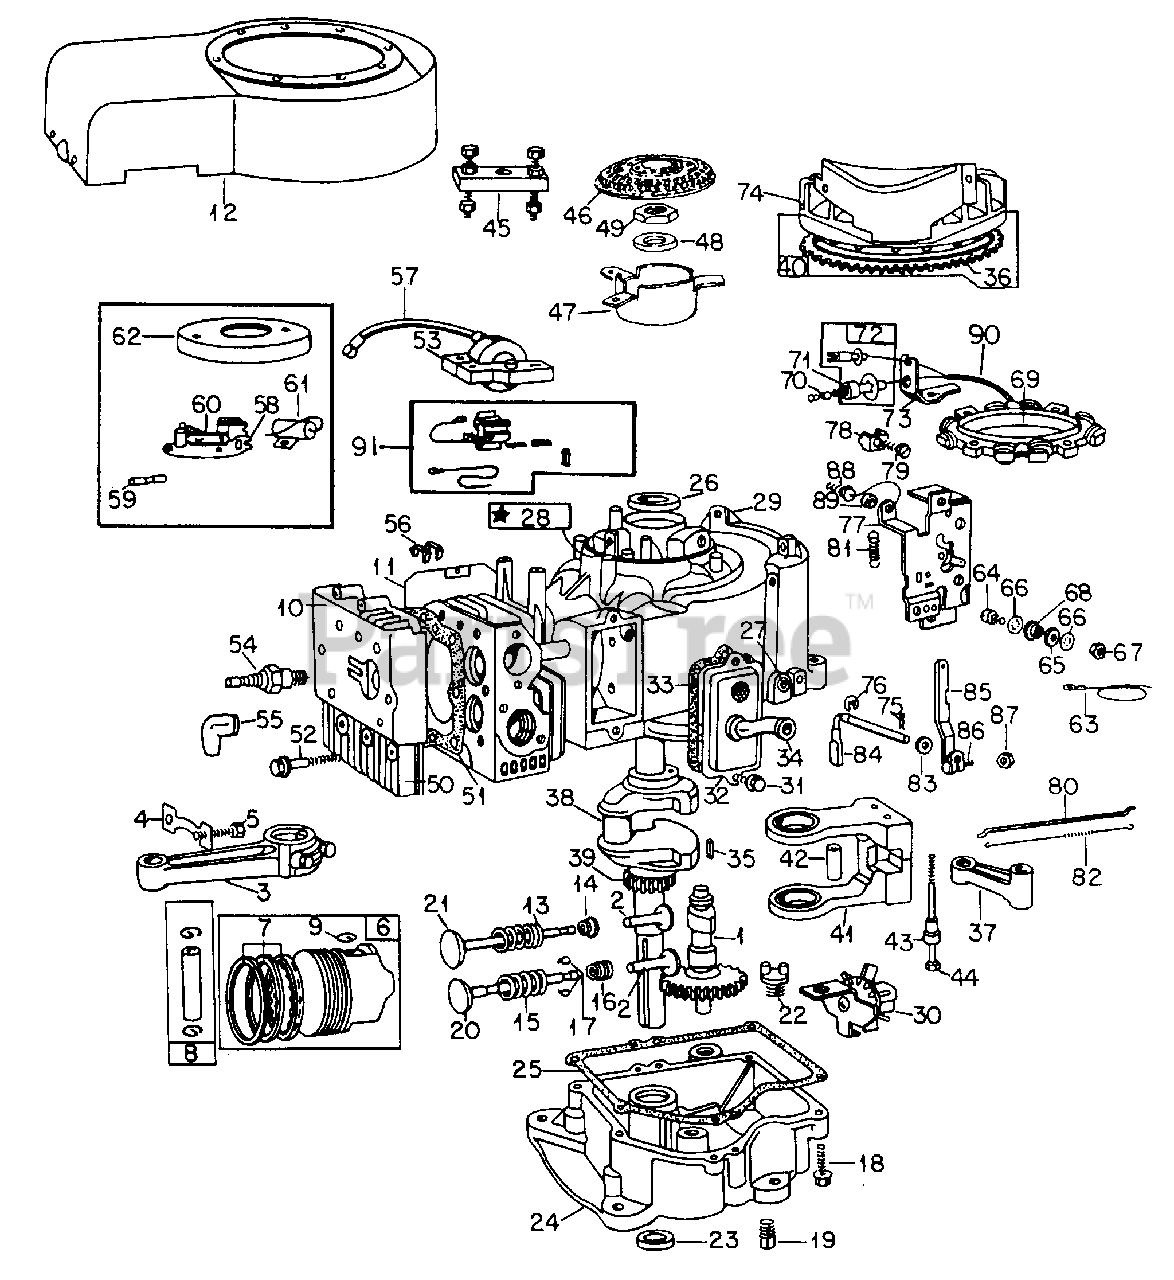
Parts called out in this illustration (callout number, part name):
1	Camshaft w/Gear
2	Tappet, Valve
3	Rod Assy, Connecting
4	Lock, Screw Head
5	Screw, Connecting Rod
6	Piston Assy, Std
7	Ring Set, Piston - Std
8	Pin Assy, Piston
9	Ring, Piston Pin Lock
10	Cover, Cylinder Head
11	Shield, Cylinder
12	Housing, Blower
13	Spring, Intake Valve
14	Retainer, Intake Valve
15	Spring, Exhaust Valve
16	Retainer, Roto-Coil
17	Roto-Coil, Exhaust Valve
18	Screw, Sump Mtg
19	Plug, 3/8-18 Auto Sq Hd Oil Drain
20	Valve, Exhaust
21	Valve, Intake
22	Plug, Oil Filler
23	Seal, Oil
24	Cover, Crankcase Oil Sump
25	Gasket, Crankcase
26	Seal, Oil
27	Bushing, Governor
28	Bushing, Plunger
29	Cylinder Assy
30	Oil Slinger, Governor Gear
31	Screw, Breather Mtg
32	Breather, Valve Chamber
33	Gasket, Breather & Valve Chamber
34	Tube, Breather
35	Key, Flywheel
36	Gear, Ring
37	Link, Counterweight
38	Crankshaft
39	Gear, Timing
40	Flywheel w/Ring Gear Assy
41	Counterweight Assy
42	Pin, Counterweight
43	Spacer, Counterweight
44	Screw, Counterweight
45	Puller, Flywheel
46	Screen, Flywheel
47	Cup, Screen Mtg
48	Washer, Spring
49	Nut, 5/8-NF
50	Head, Cylinder
51	Gasket, Cylinder Head
52	Screw, Cylinder Head
53	Armature Assy, Magneto
54	Plug, Spark - Champion
55	Elbow, Spark Plug Insul.
57	Terminal, Magneto Cable
58	Breaker Assy, Ignition
59	Plunger, Breaker Points
60	Spring, Breaker Arm
61	Condenser
62	Cover, Points & Condenser
63	Wire, Ground
64	Screw, No. 8 X 5/8 Mach Ground
65	Washer, Insulating
66	Washer, Internal Tooth Lock
67	Nut, No. 8 Mach
68	Collar, Insulating
69	Stator, Alternator
70	Diode
71	Spring, Diode
72	Holder, Fuse
73	Bracket, Fuse
74	Cover, Starter Shield
75	Cotter, Governor Crank
76	Retainer, Governor Crank
77	Plate, Governor
78	Clamp, Casting
79	Screw w/Lockwasher
80	Link, Governor
81	Spring, Governor
82	Spring, Governor Link
83	Washer, Governor Crank
84	Crank, Governor
85	Lever Assy, Governor
86	Bolt, Governor Lever
87	Nut, No. 10 Mach
88	Screw, Gov Control Plate Mtg
90	Cable Assy, Diode 8 Connector
91	Module, Ignition
